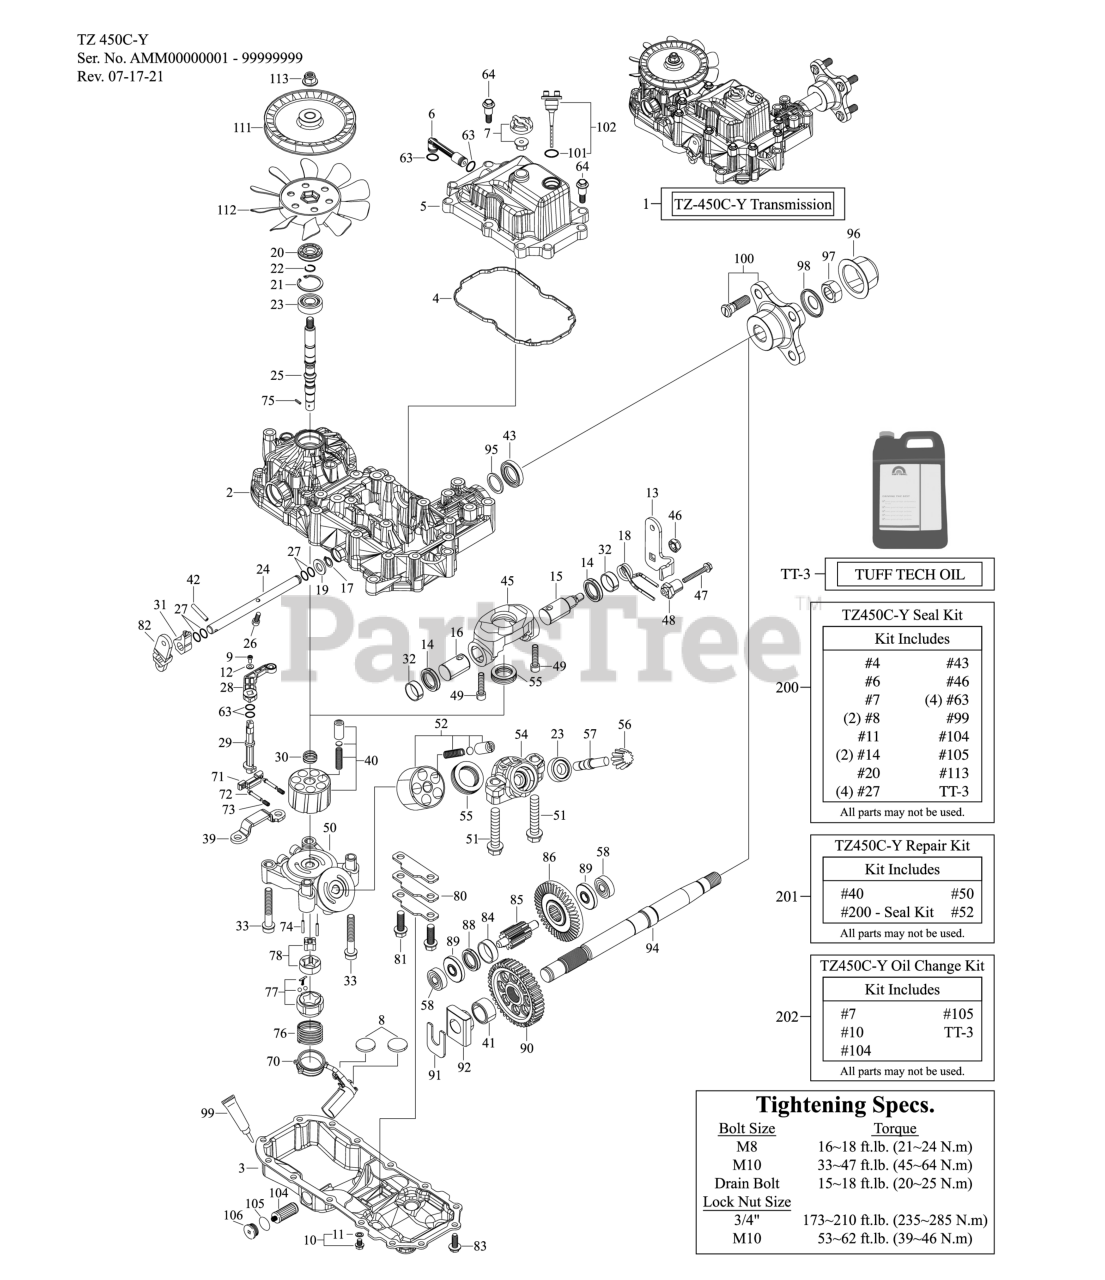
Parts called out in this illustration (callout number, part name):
1	Transaxle - Tuff Torq, RH - SZL
2	Upper Housing X
3	Lower Housing Fy
4	Square Seal
5	Top Cover A
6	Bypass Piping
7	Vent Valve
8	Magnet 28 * 3.5
9	Screw 4.0*8
10	Drain Bolt Kit
11	Washer Seal 10
12	Washer 4.5*10*1
13	Control Lever L
14	Seal, Tc253506
15	Control Shaft
16	Control Shaft Short
17	Snap Ring
18	Torsion Spring
19	Washer 12
20	Oil Seal 15*35*07
21	Snap Ring C 35
24	Brake Shaft
25	Pump Shaft C
26	Socket Bolt 6*16
27	O-Ring 1a P12
28	Bypass Lever
29	Bypass Shaft
30	Pump Spring
31	Brake Fork 20 Cr
32	Control Bush Lfb2510
33	M10 * 65 Bolt
39	Check Stopper Pfg
40	Cylinder Block Kit / Order Repair Kit
41	Bushing 25.4
42	Spring Pin 5 * 32
43	Seal Tc284008
45	Swashplate
46	Lock Nut 10
47	Bolt 6*45
49	Bolt 8 * 35
50	Centercase Cp / Order Repair Kit
51	Bolt 12*65
52	Cylinder Block Kit(Motor / Order Repair Kit
54	Motor Housing
55	Thrust Bearing
56	Motor Gear S
57	Motor Shaft
58	Bearing 6201 Cn
63	0-Ring 1a P10a
64	Tapping Bolt 8*30
70	Bracket Assy Fts
71	Bypass Guide
72	Bypass Pin
73	Bypass Spring
74	Pin 3.0 * 18
75	Pin 2.5* 9.8
76	Charge Spring
77	Pump Case
78	Rotor Set
80	Final Plate
81	Bolt 10 * 30
82	Brake Arm
83	Tapping Screw 8 * 20
84	Final Pinion Collar
85	Final Pinion Shaft
86	Reduction Gear S
88	Reduction Collar
89	Reduction Collar
90	Final Gear Sv
92	Bushing 25.4
94	Axle Shaft T
96	Nut Cap
97	Lock Nut 3/4-16
98	Flange Spacer
100	Flange Assy.
101	O-Ring 1a P16
102	Dipstick Assy.
104	Filter
105	O-Ring 1a 24040
106	Cap 40
111	Pulley,5.5
112	Fan
113	Lock Nut 10
200	Seal Kit Tz-450
201	Repair Kit Tz-450 C
202	Tz 450 Oil Change Kit
TT-3	Tuff Tech Oil (3 Liter Bottle)
